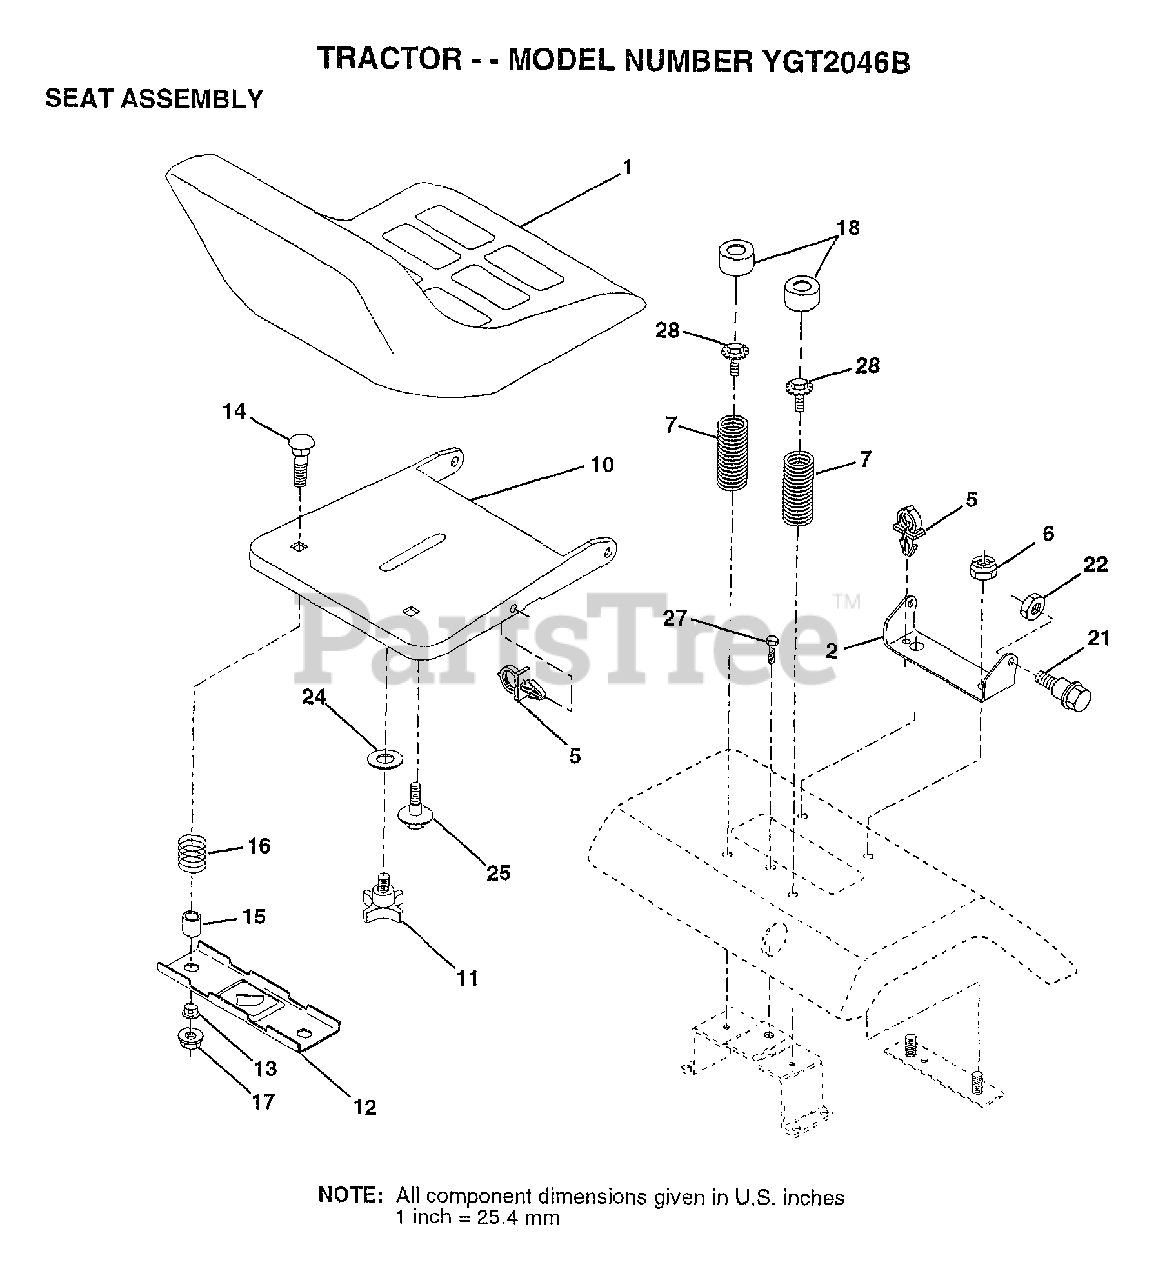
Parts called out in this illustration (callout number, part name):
2	BRACKET PVT SEAT
5	CLIP.PUSH-IN.HING
6	NUT
7	SPRING COMPRESSIO
10	PAN-SEAT
11	"KNOB 1/2"" YT"
12	BRKT SWITCH
13	BUSHING
14	BOLT-RD HD SQ NK
15	SPACER SPLIT
16	SPRING COMPRESSED
18	CAP SPRING
21	"BOLT,SHOULDER"
24	WASHER
25	"BOLT,SHOULDER"
27	SCREW LT
28	BOLT.5/16-18.UNC
